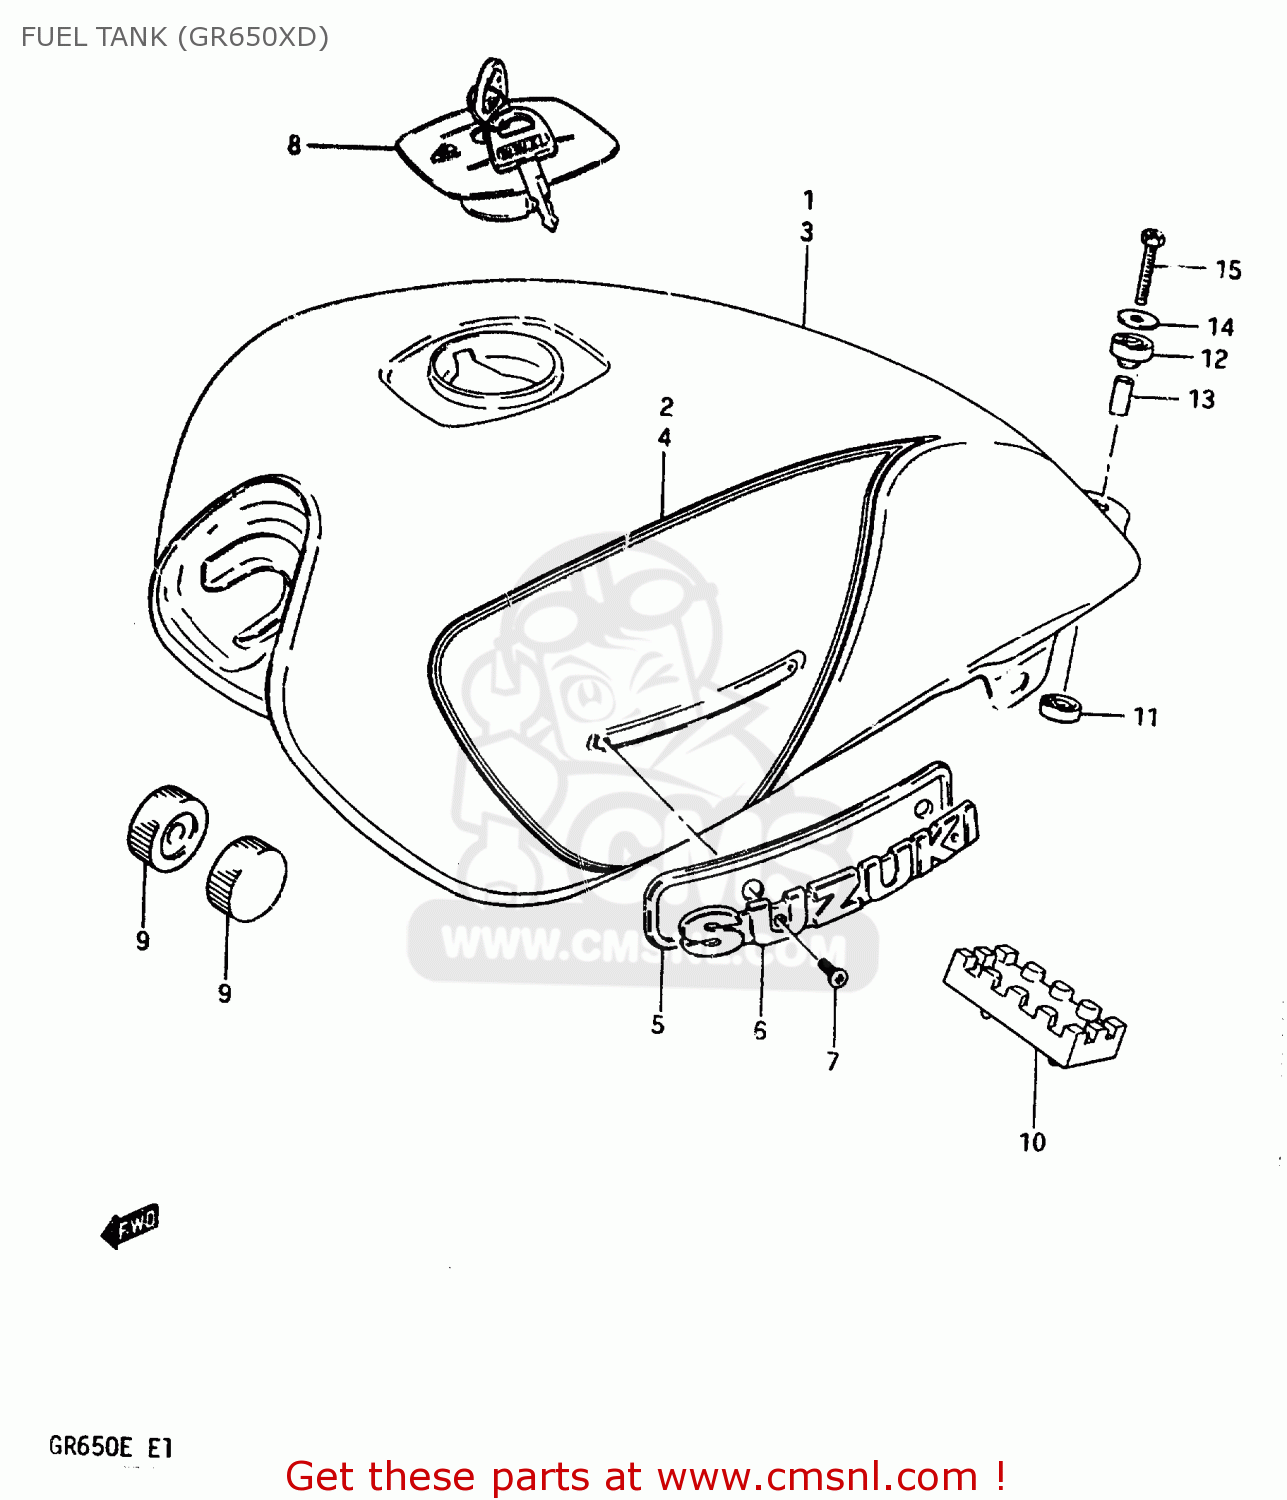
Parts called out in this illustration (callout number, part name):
1	TANK, FUEL (RED)
2	TAPE SET,FUEL TANK
3	TANK ASSY, FUEL (BLACK)
4	TAPE SET, FUEL TANK
5	CUSHION
6	EMBLEM,FUEL TANK
7	SCREW 3X6
8	CAP SET,FUEL TANK
9	CUSHION
10	CUSHION,FUEL TANK CTR
11	CUSHION
12	CUSHION
13	SPACER
14	WASHER (6.5X24X1.6)
15	BOLT
